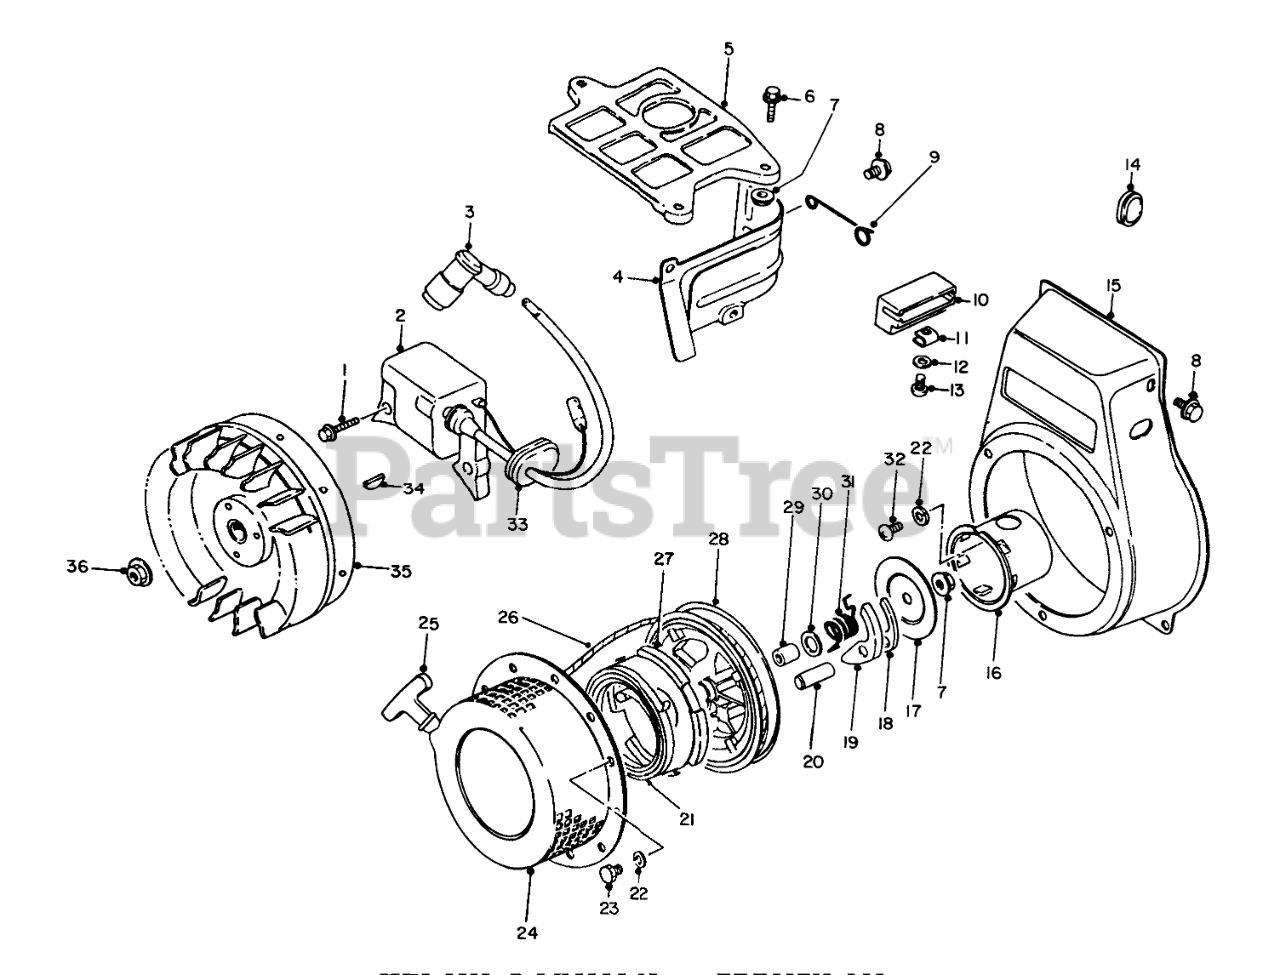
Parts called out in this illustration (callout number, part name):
2	Coil-Primary
3	SPARK PLUG CAP
4	Cowling Side
5	Cowling-Upper
9	CLAMP
10	Holder-Lead Connector
12	Washer
15	Cover-Cooling Fan
16	Pulley-Starter
17	Plate
18	Ratchet
19	Ratchet
21	SPRING
22	LOCKWASHER
24	StarterAssembly-Recoil (Incl. Ref. #7, 17-23 & 25-31)
25	Grip
26	Grip Assembly (Incl. Ref. #25)
27	SPRING CASE
29	Cover
30	Plate-Slide
31	Spring
32	Screw
33	Grommet
35	Flywheel
36	Nut
